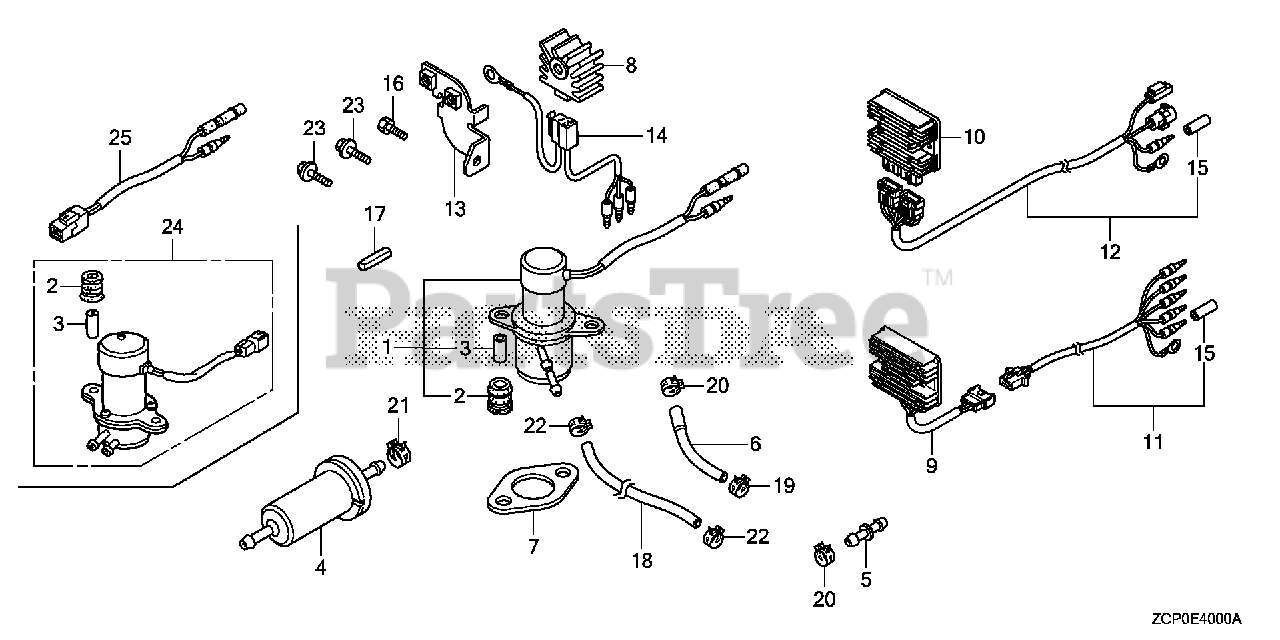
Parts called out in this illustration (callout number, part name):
7	GASKET, EX. PIPE
10	RECTIFIER ASSY., REGULATOR (30A)
12	SUB-WIRE HARNESS ASSY.
15	PLUG, CONNECTOR (OUTER)
23	BOLT, FLANGE (8X14)
